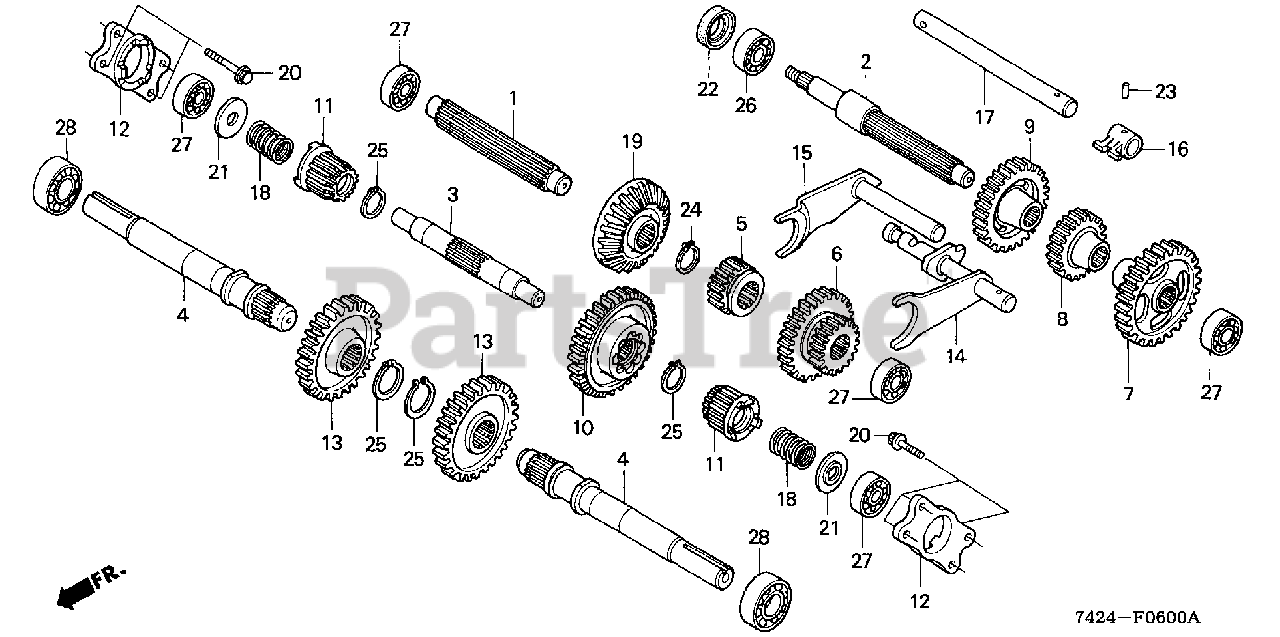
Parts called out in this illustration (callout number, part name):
1	SHAFT, INPUT
2	COUNTERSHAFT
3	SHAFT, SIDE CLUTCH
4	SHAFT, WHEEL
5	GEAR, INPUT SHAFT CHANGE (19T)
6	GEAR, CHANGE
7	GEAR, FIRST IDLE (39T)
8	GEAR, SECOND IDLE (21T)
9	GEAR, COUNTERSHAFT (36T)
10	GEAR, SIDE CLUTCH DRIVING (49T)
11	GEAR, SIDE CLUTCH (16T)
12	CASE, SIDE CLUTCH BEARING
13	GEAR, FINAL (35T)
14	FORK, INPUT SHAFT SHIFT
15	SWINGARM, SHIFT
16	ARM, FORK SELECTING
17	SHAFT, SHIFTING
18	SPRING, SIDE CLUTCH
19	GEAR, DRIVEN BEVEL (24T)
20	BOLT, SPECIAL (8MM)
21	WASHER, CLUTCH SPRING
22	OIL SEAL (20X31X7)
23	PIN, SPRING (5X22)
24	CIRCLIP (OUTER) (22MM)
25	CIRCLIP (OUTER) (25MM)
26	BEARING, RADIAL BALL (6004)
27	BEARING, RADIAL BALL (6203)
28	BEARING, RADIAL BALL (6205)
